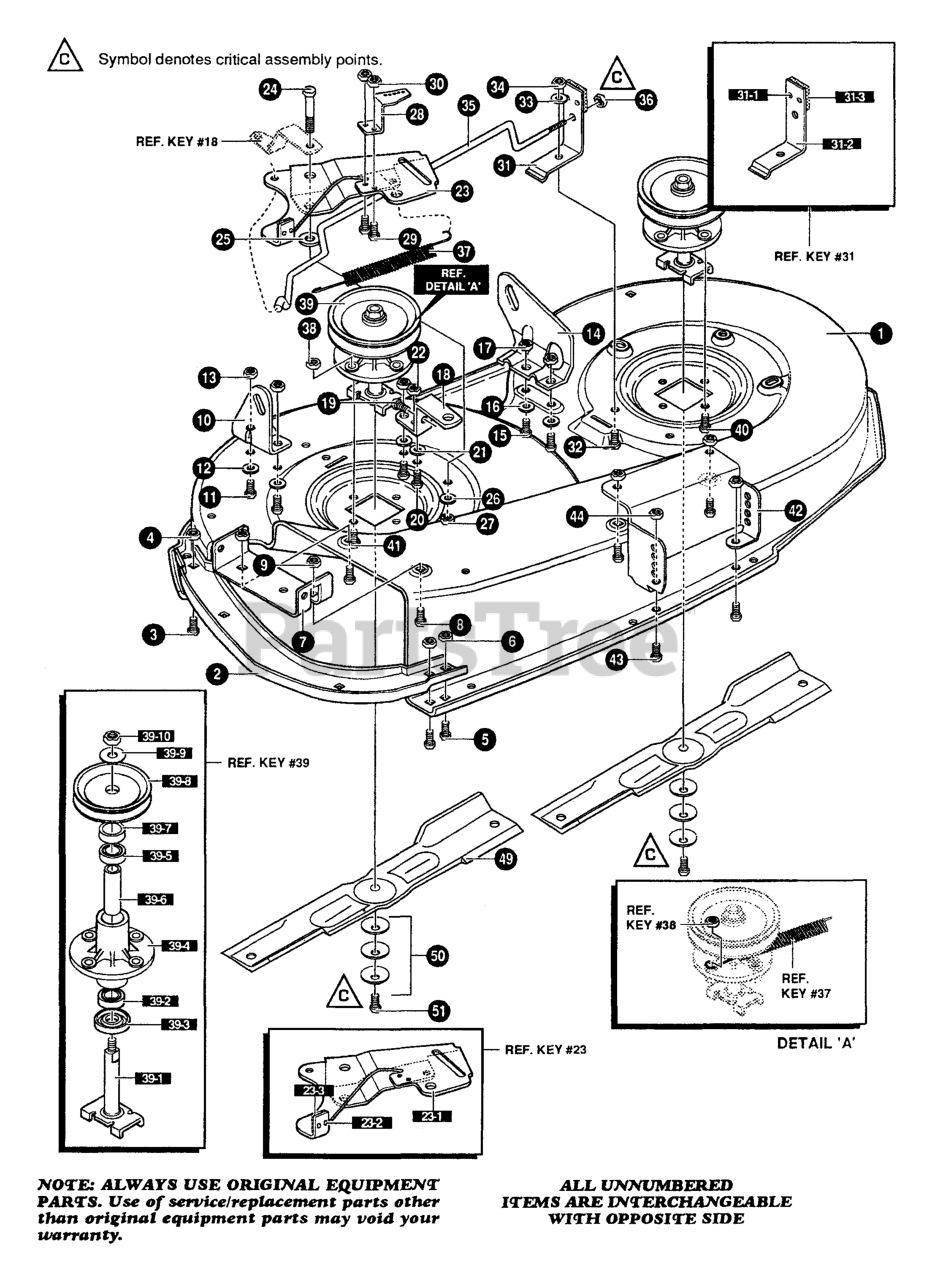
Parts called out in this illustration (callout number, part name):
1	40" DECK KIT
2	TOE GUARD
3	SCREW, 5/16-18 x 0.75
4	NUT, 5/16-18
5	SCREW, 5/16-18 x 0.75
6	NUT, 5/16-18
7	BRACKET CHUTE MOUNT
8	SCREW, 5/16-18 x 0.75
9	NUT, 5/16-18
10	BRACKET, RH LIFT REAR
11	SCREW, 5/16-18 x 0.75
12	WASHER, FLAT .344 X .69 X .065
13	NUT, 5/16-18
14	BRACKET, LH LIFT REAR
15	SCREW, 5/16-18 x 0.75
16	WASHER, FLAT .344 X .69 x .065
17	NUT, 5/16-18
18	BRACE, IDLER SUPPORT
19	SCREW, 1/4-20 x 1.25
20	SCREW, 5/16-18 x 0.75
21	WASHER, FLAT .344 x .69 X .065
22	NUT, 5/16-18
23	IDLER ARM ASSEMBLY
23-1	ARM IDLER
23-2	RIVET
23-3	BRAKE PAD - HARD
24	BOLT, .500 X 2.15
25	WASHER, FLAT .391 X 1.00 X .209
26	WASHER, FLAT .391 X 1.00 X. 125
27	NUT, 3/8-16
28	BRACKET, EXTENSION IDLER
29	SCREW, 5/16-18 x 0.75
30	NUT, 5/16-18
31	BLADE BRAKE ASSEMBLY
31-2	BRAKE ARM
31-3	BRAKE PAD - HARD
32	SCREW, 5/16-18 x 0.75
33	WASHER, FLAT .344 X .69 X .065
34	NUT, 5/16-18
35	ROD, BRAKE
36	NUT, 1/4-20
37	SPRING
38	NUT, 5/16-18
39	QUILL ASSEMBLY
39-1	SHAFT/SADDLE
39-2	BEARING, BALL
39-3	DUST SHIELD
39-4	QUILL CASTING
39-5	BEARING, BALL
39-6	SPACER, SLEEVE
39-7	SPACER, QUILL
39-8	PULLEY, QUILL V5L
39-9	WASHER, SPECIAL QUILL
39-10	NUT, 7/16-20
40	SCREW, 5/16-18 x 0.75
41	SCREW, 5/16-18 x 1.38
42	BRACKET, FRONT DECK
43	SCREW, 5/16-1 x 0.75
44	NUT, 5/16-18
49	BLADE, 20.32
50	WASHER, .391D X 1.25D X .07
51	SCREW, 3/8-24 X 1.00
